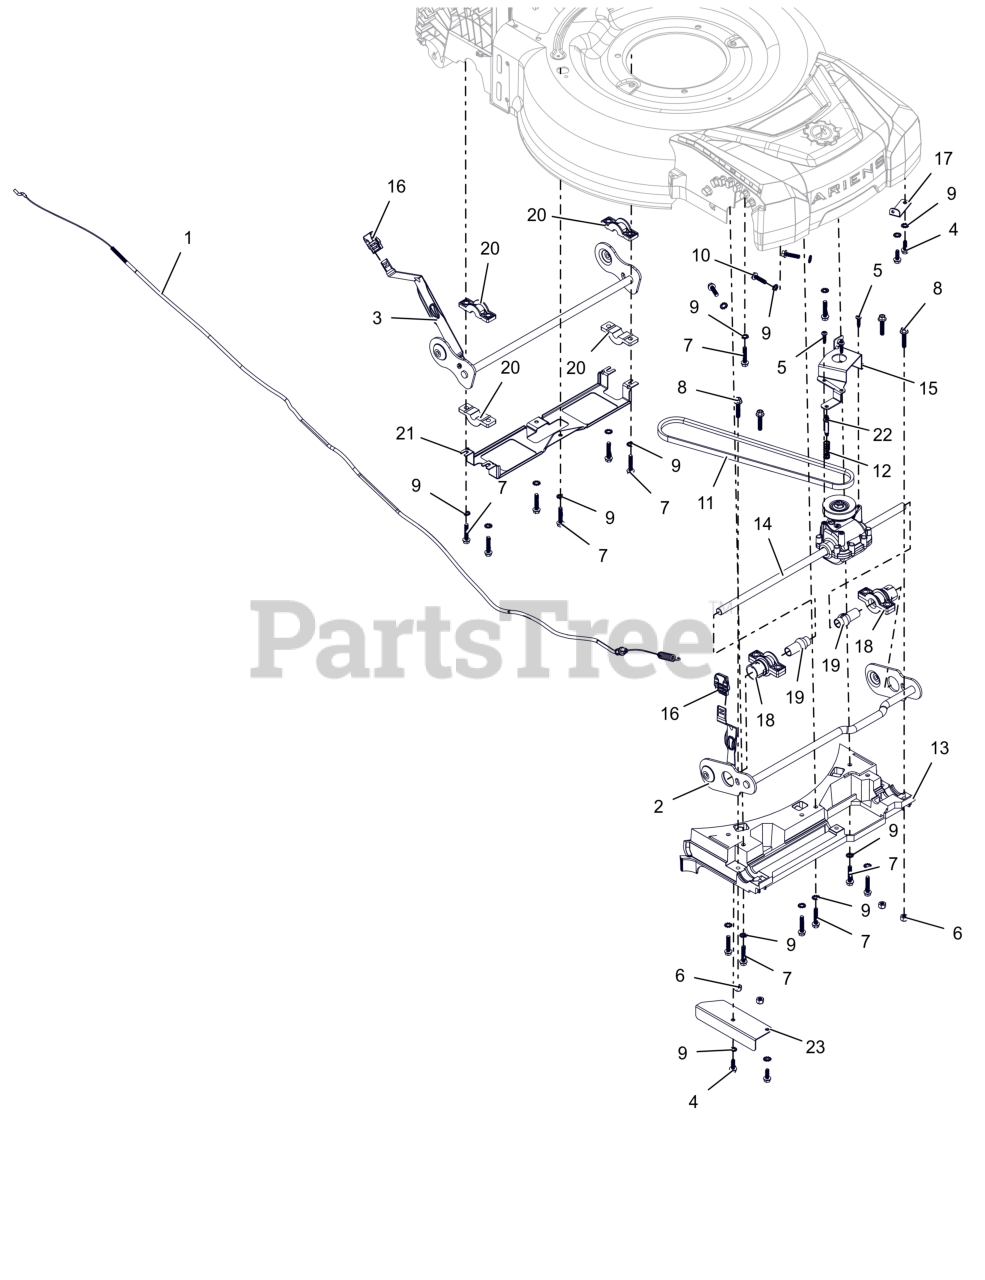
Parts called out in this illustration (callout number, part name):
1	CABLE, FWD TRANSMISSION
2	WLDMT, FRONT AXLE - SP (BLACK)
3	WLDMT, REAR AXLE - PUSH (BLACK)
4	SCR, HI-LO HWH 1/4-15 X .750
5	SCR, TORX TRILOB PH 10-14X.75
6	NUT, NYLOC 1/4-20
7	SCR, HI-LO HWH 1/4-15 X 1.25
8	BLT, HWH 1/4-20 X 1.25
9	WSHR-LK-EXT, .256X.510X.028
10	SCR, HI-LO HWH 1/4-15 X 1.00
11	BELT, FWD
12	SPRG, ADJUSTER KNOB
13	TRAY, FRONT
14	ASM, FWD TRANSMISSION - MA 300
15	BRKT, FWD TRANSMISSION
16	GRIP, HOC
17	PLATE, CABLE ANCHOR (BLACK)
18	BUSHING, AXLE - OUTER
19	BUSHING, AXLE - INNER
20	BUSHING, SHAFT - HOC
21	BRKT, BACK SUPPORT (BLACK)
22	HOLDER, RETURN SPRING
23	FLANGE, BLOW OUT (BLACK)
